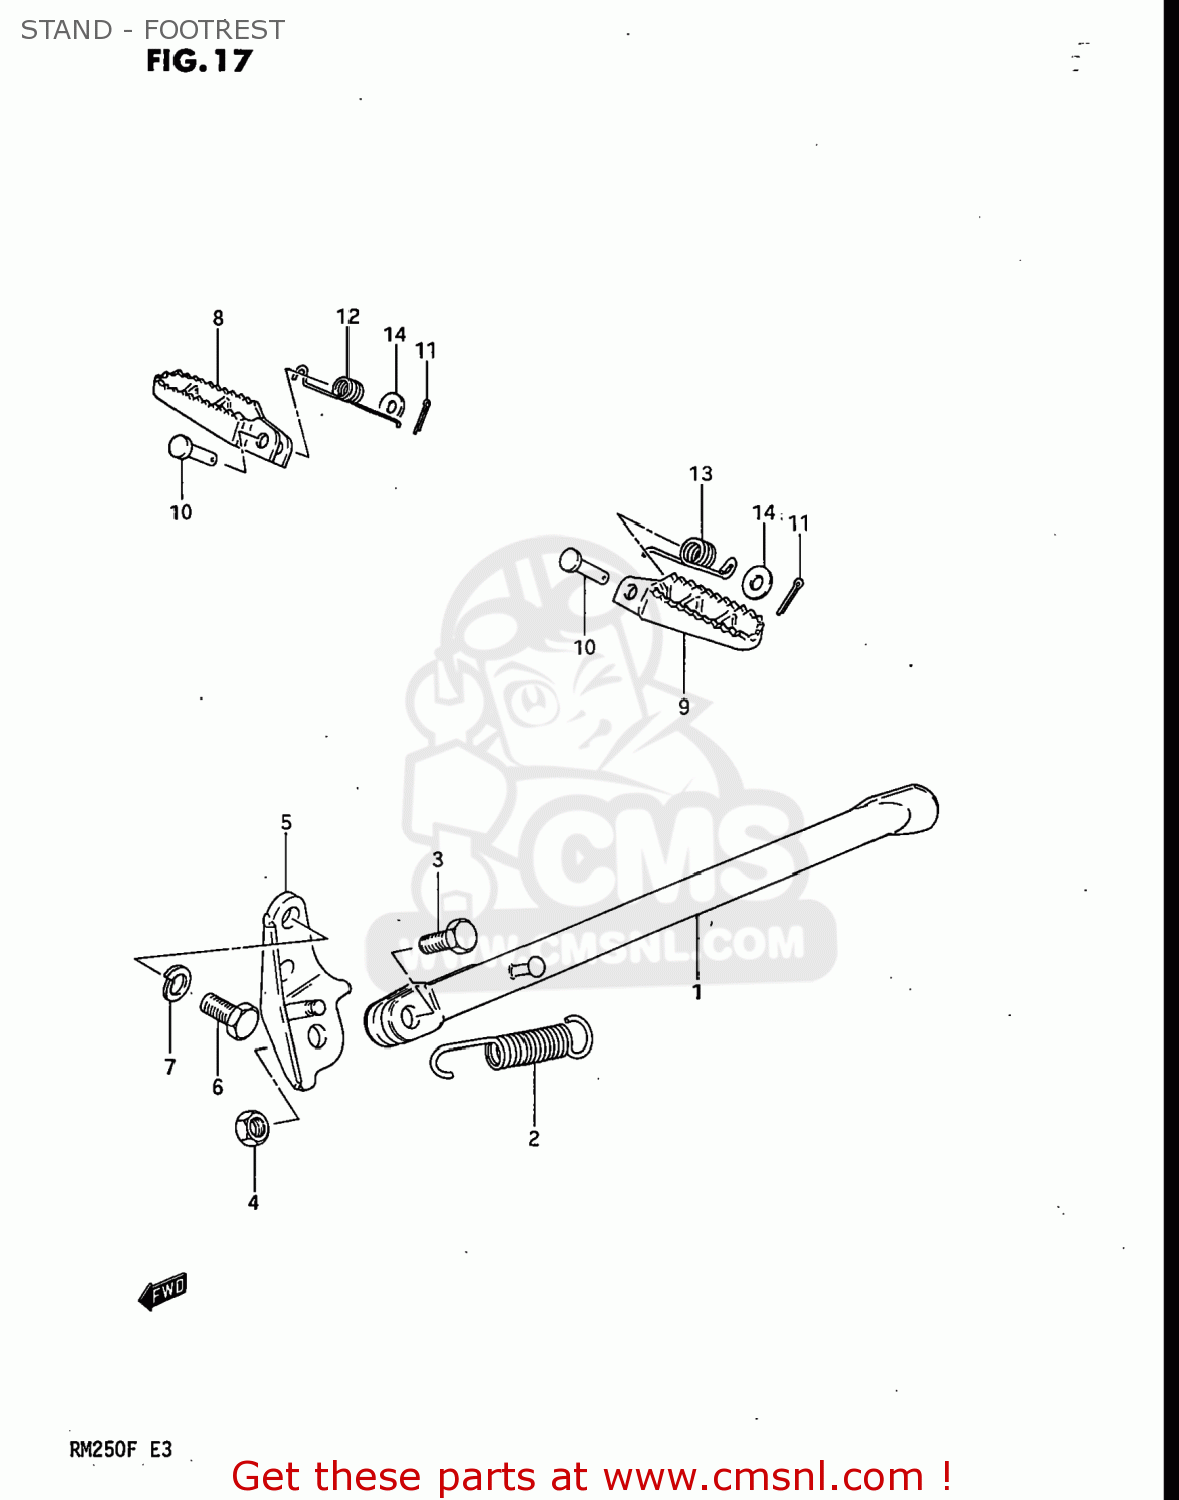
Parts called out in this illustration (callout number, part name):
1	STAND,SIDE
2	SPRING
3	BOLT(10X30)
4	NUT
5	BRACKET,SIDE STAND
6	BOLT(10X19)
7	LOCK WASHER
8	FOOTREST
9	FOOTREST
10	PIN
11	PIN 20X20
12	SPRING,FOOTREST,RIGHT
13	SPRING,FOOTREST LH
14	WASHER
